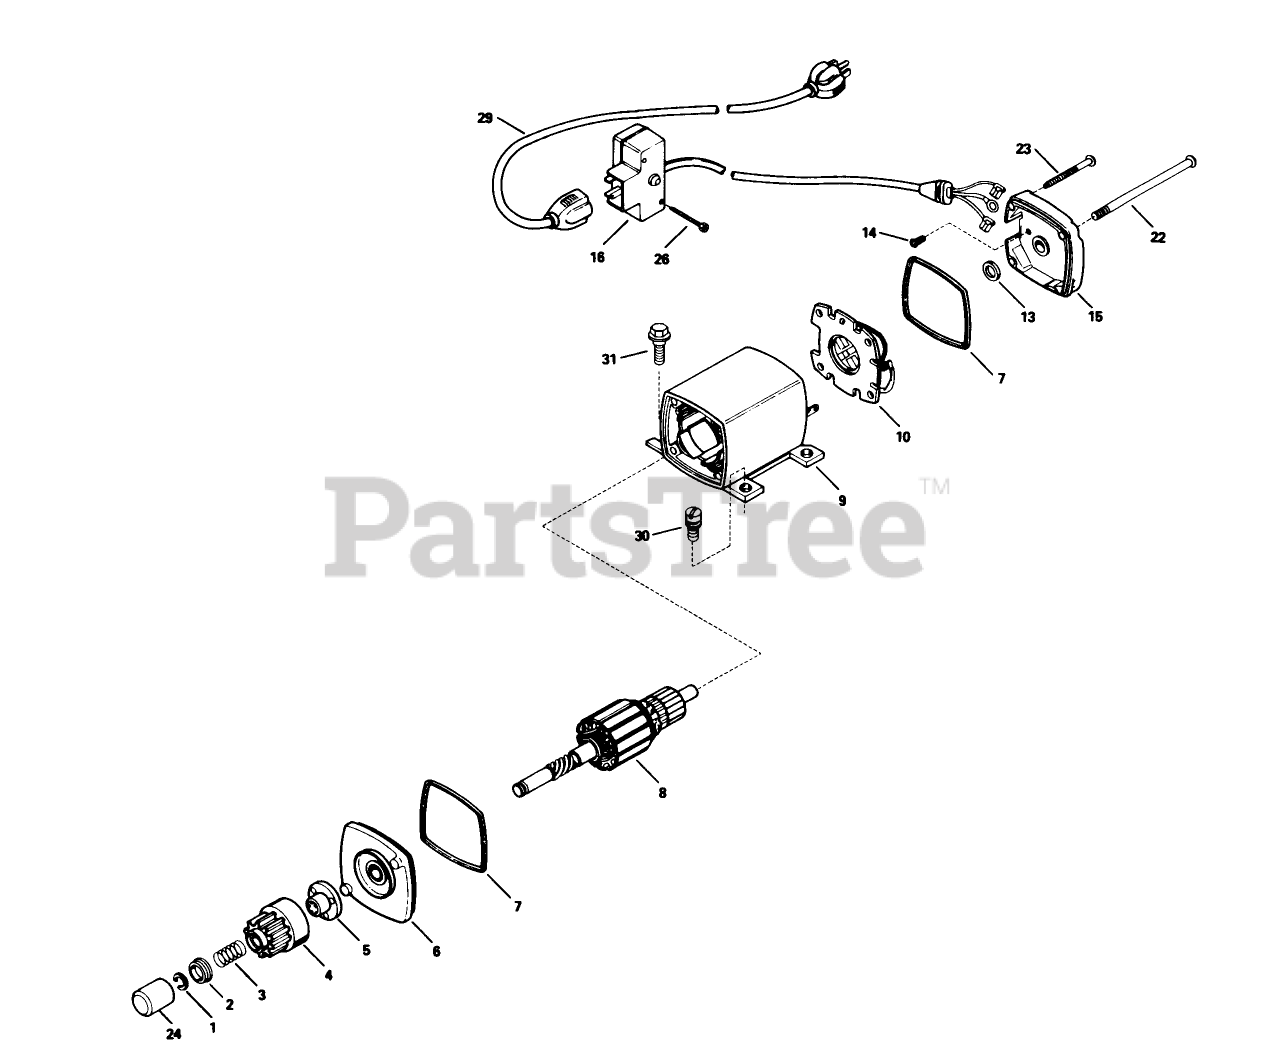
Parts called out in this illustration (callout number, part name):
1	Ring-Retainer
2	Retainer-Spring
3	Spring-Anti Drift
4	Gear
5	Nut-Engaging
6	Cap Assembly-Cap End (Incl. Ref. #7)
7	O-Ring
8	Armature
9	Housing Assy.
10	Card ASM
13	Washer-Thrust
14	Screw-Ground
15	Cap Assembly (Incl. Ref. #7)
16	Box Assembly-Switch (Incl. Ref. #26)
22	Bolt-Case
23	Screw-Ground
24	Cover-Dust
26	Screw
29	Cord-Extension
30	Screw
31	Screw (1/4-20x1/2)
